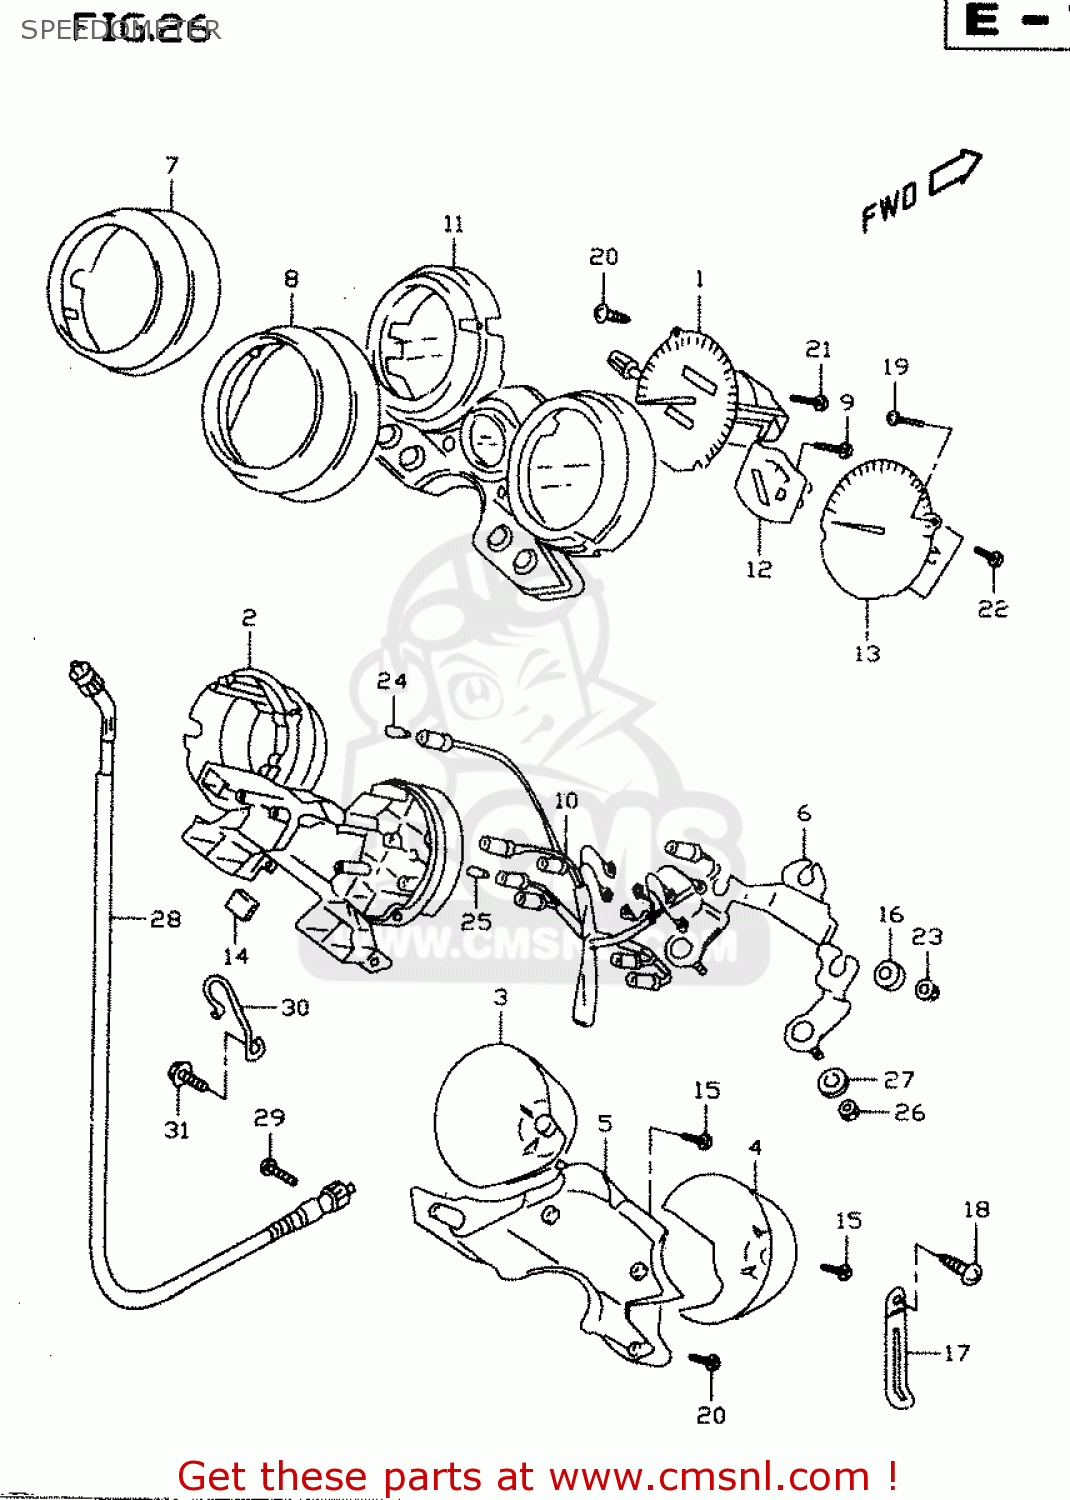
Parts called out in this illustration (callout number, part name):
1	SPEEDOMETER
2	CASE
3	CASE,LWR SPEEDOMETER
4	CASE,TACHOMETER LWR
5	CASE,PILOT BOX LWR
6	BRACKET,SPEEDOMETER
7	PLATE
8	RING
9	SCREW(3X21.2)
10	SOCKET,SPEEDOM
11	CASE ASSY,SPEEDOMETER
12	BODY ASSY,FUEL METER
13	TACHOMETER
14	LENS
15	SCREW(4X14)
16	CUSHION,METER
17	CLAMP(L:97)
18	SCREW
19	SCREW(3X10)
20	SCREW(4X14)
21	SCREW
22	SCREW
23	NUT
24	BULB(12V1.7W,T6.5)
25	BULB(12V3W,T6.5)
26	NUT 6MM
27	WASHER(6.5X24X1.2)
28	CABLE ASSY,SPEEDOMETER
29	SCREW
30	GUIDE,SPEEDOMETER CABLE NO.1
31	BOLT
